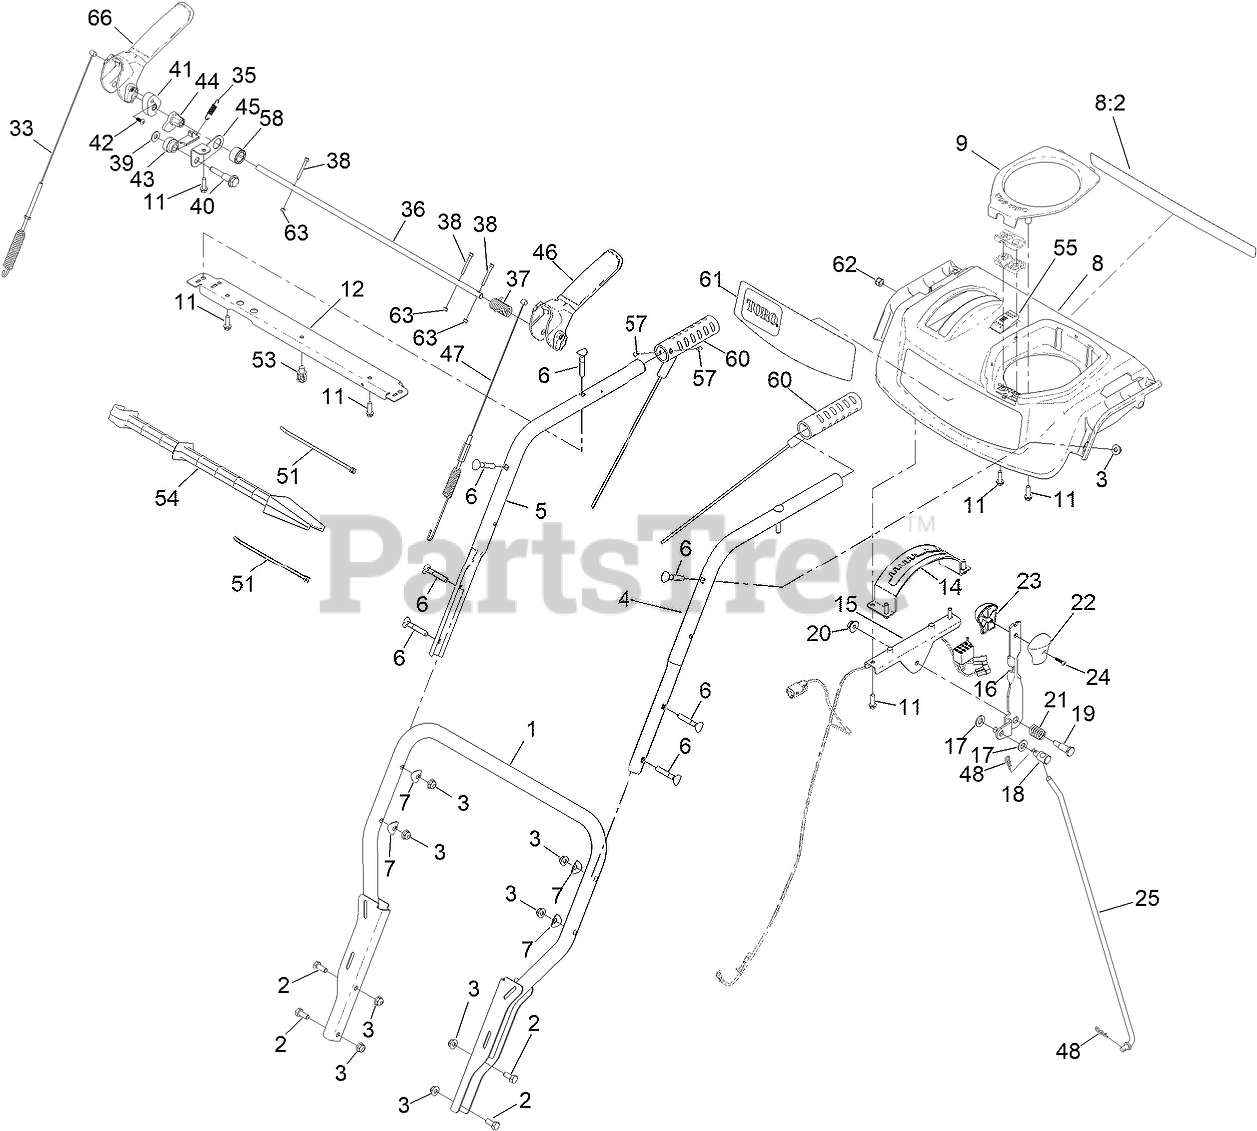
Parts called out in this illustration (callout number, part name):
1	HANDLE-LOWER, WELD ASM
2	SCREW-HH
3	NUT-HF
4	HANDLE-UPPER, LH
5	HANDLE-UPPER, RH
6	SCREW-HANDLE
7	WASHER-CUP
8	CONTROL PANEL ASSEMBLY
8:2	DECAL-SAFETY
9	COVER-QUICKSTICK
11	SCREW-PLASTITE, HWH
12	BRACE-CONSOLE
14	GATE-SHIFT
15	BRACKET-SHIFT
16	SELECTOR-SPEED
17	WASHER-FLAT
18	TRUNNION-ROD
19	SCREW-SHOULDER, HH
20	NUT-HF
21	SPRING-COMPRESSION
22	KNOB-SHIFT, LH
23	KNOB-SHIFT, RH
24	SCREW-PPH
25	ROD-SHIFT
33	CABLE-AUGER
35	SPRING-LOCKOUT, HANDLE
36	ROD-LOCKOUT
37	SPRING-TORSION, HANDLE RETURN
38	SCREW-HSH
39	WASHER-FLAT
40	SCREW-SHOULDER
41	HANDLE LOCK
42	SCREW-PPH
43	LATCH, LOCKOUT
44	CAM-LOCKOUT
45	LINK-LOCKOUT
46	LEVER-CONTROL
47	CABLE-TRACTION
48	PIN-HAIR
51	TIE-CABLE
53	CLIP-TIE
54	STICK-CLEANOUT
55	SWITCH-ROCKER, ON-NONE-OFF (HEATER)
57	RIVET-POP
58	COLLAR-CAM
60	GRIP-HEATED
61	DECAL-CONSOLE
62	NUT-HEX
63	NUT-LOCK ROHS
66	AUGER CONTROL ASM
